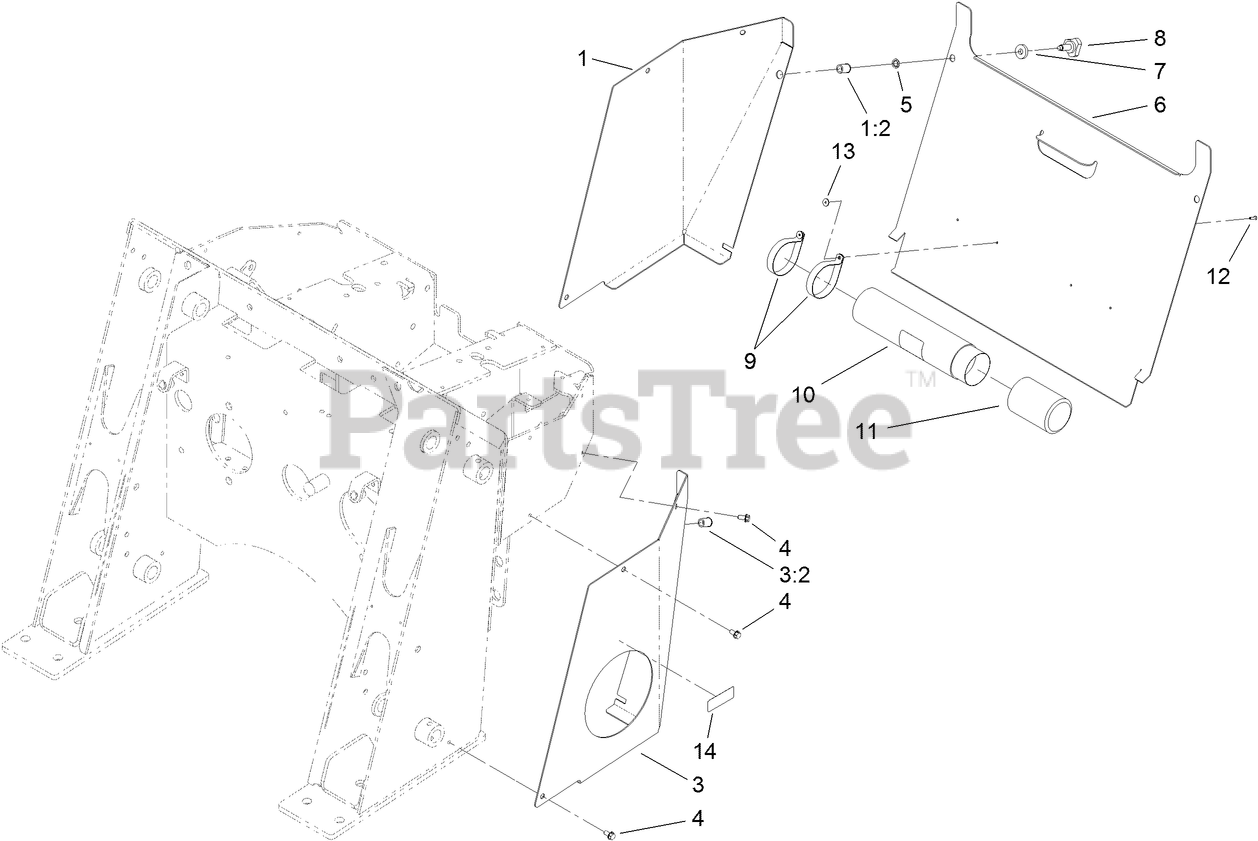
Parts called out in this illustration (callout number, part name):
1	RH REAR COVER SUPPORT ASM
1:2	NUT-CLINCH
3	LH REAR COVER SUPPORT ASM
3:2	NUT-CLINCH
4	SCREW-HWH
5	RING-RETAINING
6	COVER-ACCESS, REAR
7	WASHER-RUBBER
9	CLAMP-R
10	TUBE-MANUAL
11	CAP-HOUSING
12	RIVET-POP
13	WASHER-BACK
14	DECAL-DIESEL
